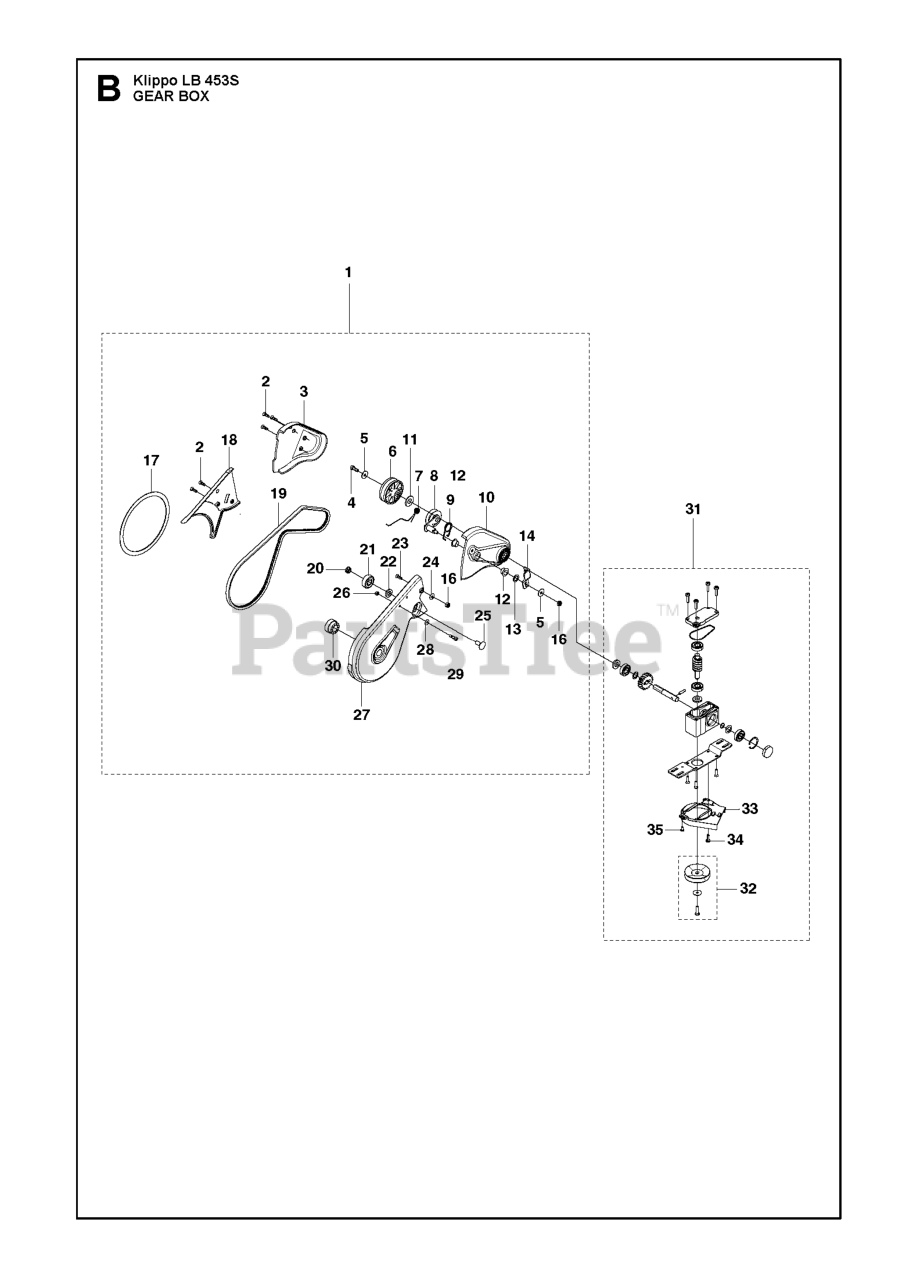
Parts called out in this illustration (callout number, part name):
2	FILTER COVER
3	AIR FILTER
8	CHOKE CONTROL
11	CARBURETOR
